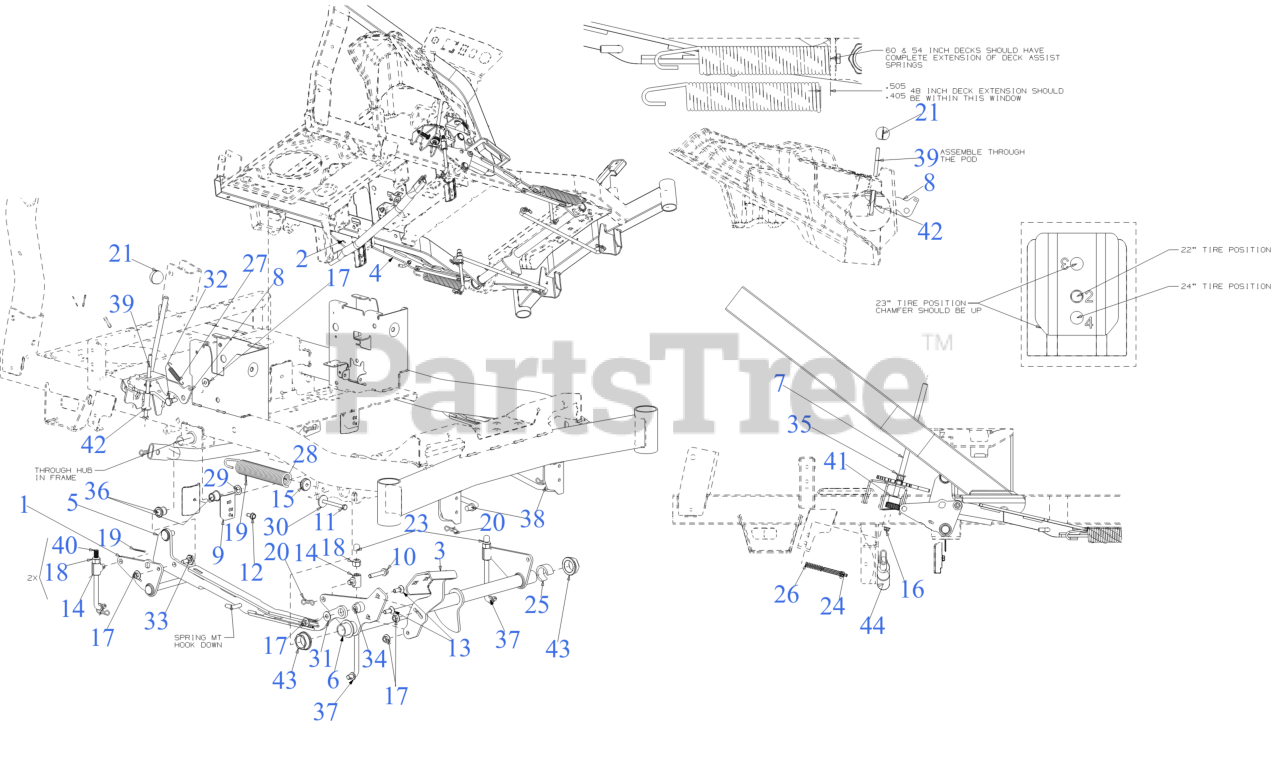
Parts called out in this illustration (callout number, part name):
1	BELLCRANK BRACKET (RH)
2	BELLCRANK BRACKET (LH)
3	DECK LIFT PEDAL
4	LIFT LINK (LH)
5	LIFT LINK (RH)
6	LIFT TUBE (FRONT)
7	DECK HEIGHT ADJUSTMENT ROD
8	TRAVEL LOCK PLATE
9	UPSTOP BRACKET
10	SCREW 3/8-16 x 2.00 GR5
11	SCREW 5/16-18 x 3.50 GR5
12	SCREW 5/16-18 x .750
13	CARRIAGE BOLT 3/8-16 x 1.00 GR5
14	LIFT ROD FERRULE
15	LIFT SPRING INSERT
16	FLANGE LOCK NUT 5/16-18
17	FLANGE LOCK NUT
18	HEX LOCK NUT NYLON
19	COTTER PIN
20	BOW TIE COTTER PIN
21	BALL KNOB
23	LIFT ROD END CAP
24	DETENT PLUNGER
25	LIFT TUBE SPACER
26	COMPRESSION SPRING .531 OD 1.75 LG
27	EXTENSION SPRING 2.675"
28	EXTENSION SPRING
29	FLAT WASHER
30	WASHER-5/16 x 1.25X 1.27
31	WASHER-.395 x 1.0 x .62
32	SHOULDER SCREW
33	SHOULDER SCREW .50 x .385
34	SHOLUDER SPACER
35	HEX FLANGE BEARING .506ID x .590LG
36	FLANGE BUSHING
37	DECK LIFT ROD 6.875"
38	DECK CONTROL ROD
39	TRAVEL LOCK ROD
40	DECK LIFT ROD 6.250"
41	DECK HEIGHT DETENT HUB
42	LOCK ROD SLEEVE SPACER
43	FLANGE BEARING
44	DECK STABILIZER TUBE
